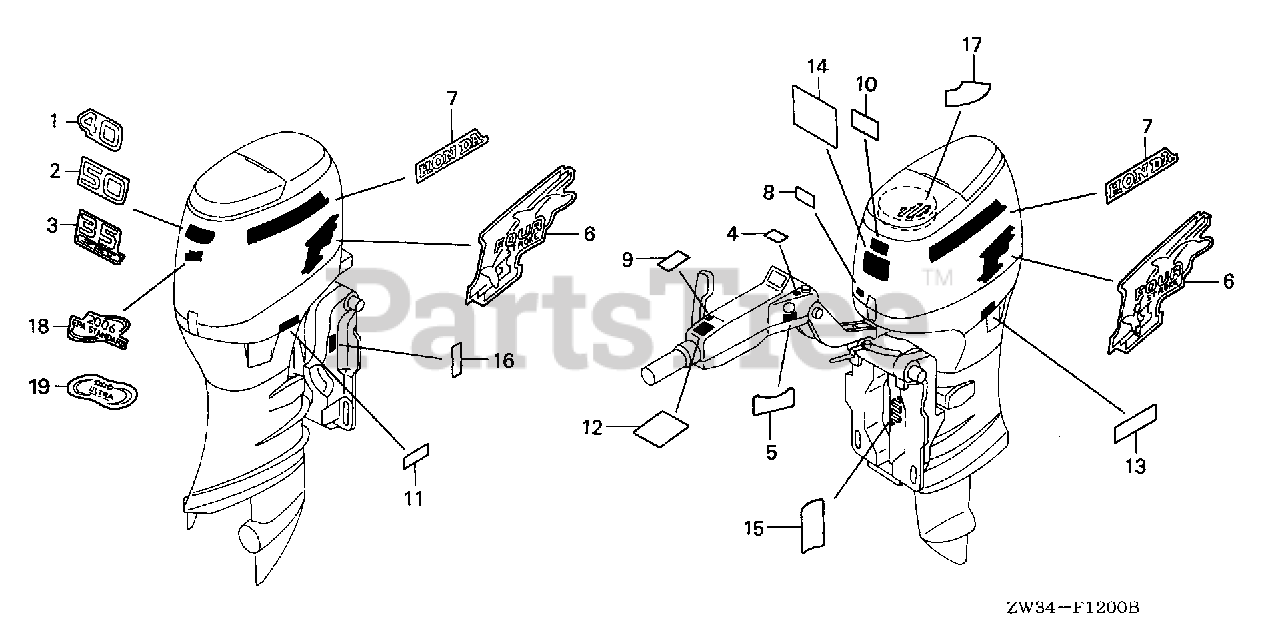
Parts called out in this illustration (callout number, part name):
3	MARK, RR. (BF35 JET)
6	MARK, SIDE
7	MARK, SIDE STRIPE
8	MARK (E-SPEC)
10	LABEL, CAUTION OPERATOR (ENGLISH)
11	LABEL, OIL CAUTION (ENGLISH)
13	LABEL, STORING CAUTION (ENGLISH)
17	MARK, EMERGENCY START (ENGLISH)
